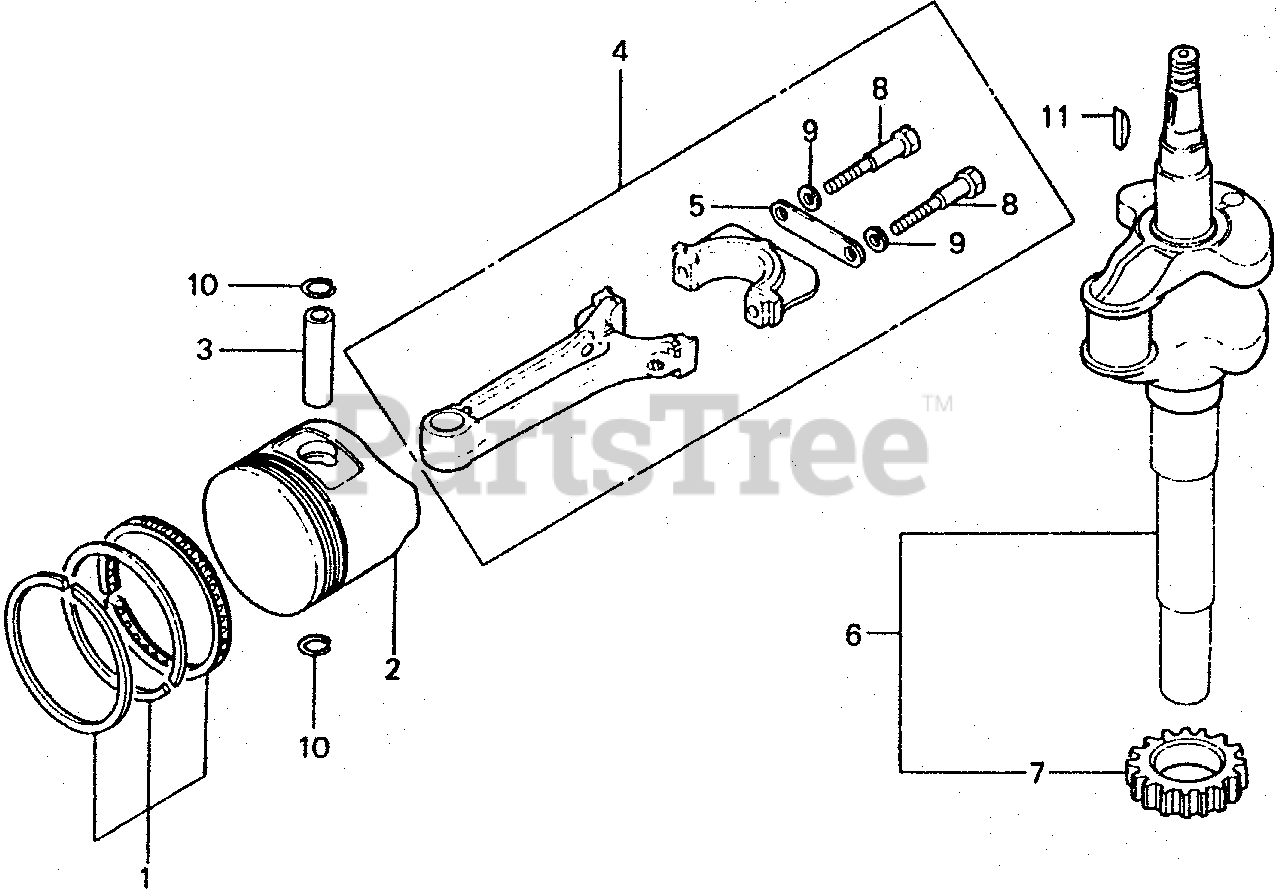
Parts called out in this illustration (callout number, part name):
1	RING SET, PISTON (STD)
1	RING SET, PISTON (0.25) (NOT AVAILABLE)
1	RING SET, PISTON (0.50) (NOT AVAILABLE)
1	RING SET, PISTON (0.75) (NOT AVAILABLE)
2	PISTON (STD)
2	PISTON (0.25)
2	PISTON (0.50)
2	PISTON (0.75) (NOT AVAILABLE)
3	PIN, PISTON
4	ROD ASSY., CONNECTING
4	ROD ASSY., CONNECTING (UNDER SIZE) (NOT AVAILABLE)
5	WASHER, CONNECTING ROD
6	CRANKSHAFT (NOT AVAILABLE)
7	GEAR, TIMING
8	BOLT, CONNECTING ROD (7MM)
9	WASHER, LOCK (7MM)
10	CLIP, PISTON PIN (15MM)
11	KEY, SPECIAL WOODRUFF (25X18)
